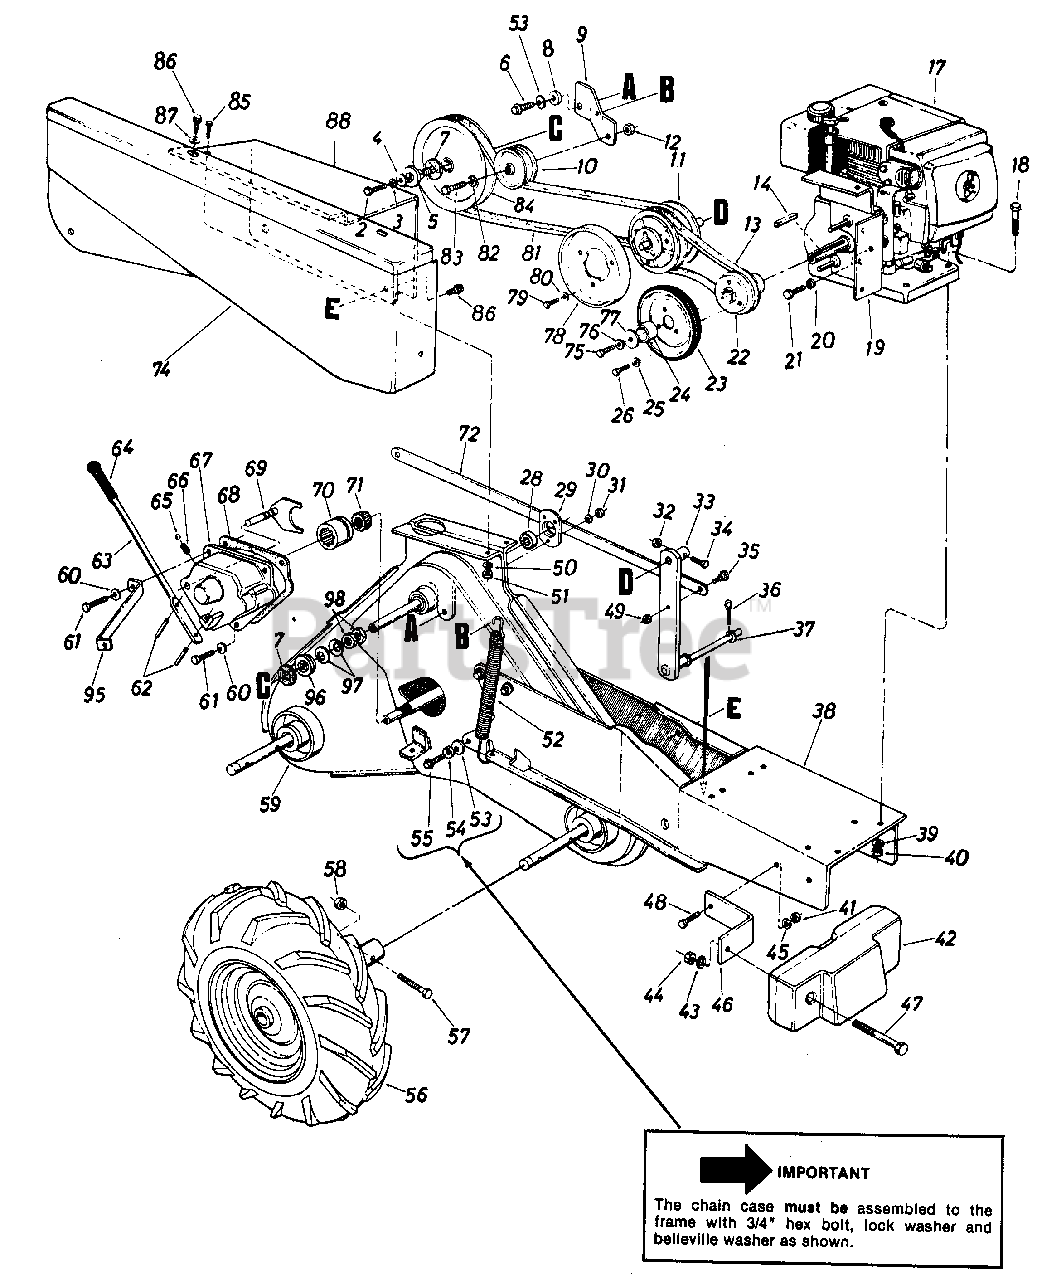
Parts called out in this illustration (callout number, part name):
2	Hex L-Bolt 5/16-24 x 1.5" Lg.*
3	L-Wash. 5/16" I.D.
4	Fl-Wash. 5/16" I.D. x 1.125" O.D.
5	Friction Disc Ass'y.
6	Hex Bolt 3/8-24 x 1.25" Lg.
7	Friction Pad
8	Shoulder Spacer
9	Idler Bracket
10	Fl-ldler 2.75" Dia.
11	Variable Speed Ass'y.
12	Hex Ins. L-Nut 3/8-16 Thd.
13	V-Belt 5/8" x 27.0" Lg.
14	Sq. Key 1/4" x 2.00" Lg.*
17	Engine
18	Hex Bolt 5/16-18 x 1.75" Lg.*
19	Belt Cover Support Ass'y.
20	Internal L-Wash. 1/2" I.D.
21	Hex Bolt 1/2-20 x .75" Lg.
22	Engine Pulley Ass'y.
23	Friction Wheel Ass'y.
24	Spacer
25	L-Wash. 5/16" I.D.*
26	Hex Bolt 5/16-18 x .50" Lg.*
28	Ball Bearing
29	Bearing Housing 1-3/8" O.D.
30	L-Wash. 1/4" I.D.*
31	Hex Nut 1/4-28 Thd.*
32	Hex Ins. L-Nut 1/4-20 Thd.
33	Variable Speed Brkt. Ass'y.
34	Hex Bolt 1/4-20 x 1.25" Lg.*
35	Shld. Bolt 1/2" Dia. x .25" Lg.
36	Cotter Pin 1/8" Dia. x 1.0" Lg.*
37	Fl-Wash. .686" I.D. x 1.25" O.D.
38	Frame Ass'y.
39	L-Wash. 5/16" I.D.*
40	Hex Nut 5/16-18 Thd.*
41	Hex Cent. L-Nut 3/8-24 Thd.
42	Weight
43	Fl-Wash. .50" I.D. x 1.0" O.D.
44	Hex Nut 1/2-13 Thd.*
45	L-Wash. 3/8" I.D.'
46	Weight Mtg. Brkt.
47	Hex Bolt 1/2-13 x 4.50" Lg.*
48	Hex Bolt 3/8-24 x 1.00" Lg.*
49	Hex Ins. L-Nut 3/8-16 Thd.
50	L-Wash. 1/4" I.D.*
51	Hex Cent. L-Nut 1/4-28 Thd.
52	Spring Idler Bracket
53	Belleville Wash. 3/8" I.D.
54	L-Wash. 3/8" I.D.*
55	Hex Self-Tap Scr. 3/8-16 x .75" Lg.
56	Wheel Ass'y. Comp. R.H.
56	Wheel Ass'y. Comp. L.H.
57	Hex Bolt 3/8-24 x 1.25" Lg.*
58	Hex Ins. L-Nut 3/8-24 Thd.
59	Chain Case Ass'y. Comp.
60	L-Wash. 5/16" I.D.*
61	Hex Tap Tite Scr. 5/16-18 x .75" Lg.
62	Headed Spiral Pin 3/16 x 13/16" Lg.
63	Engagement Lever
64	Grip
65	Ball Detent.250" Dia.
66	Compression Spring
67	Shift Housing R.H.
67	Shift Housing L.H.
68	Gasket Shift Housing
69	Shift Yoke Ass'y. R.H.
69	Shift Yoke Ass'y. L.H.
70	Clutch Dog
71	Clutch Dog Driver
72	Control Brkt.
74	Shroud Belt Cover
75	Hex Bolt 7/16-20 x 2.25" Lg.
76	L-Wash. 7/16" I.D.
77	Fl-Wash. .44 I.D. x 1.38" O.D.
78	Friction Disc
79	Hex Bolt 1/4-28 x .50" Lg.
80	L-Wash. 1/4" I.D.*
81	V-Belt 5/8" x 51" Lg.
82	L-Wash. 3/8" I.D.*
83	Hex Bolt 3/8" x 1.50" Lg.*
84	Input Pulley Chain Case
85	Hex Bolt 1/4-28 x .62" Lg.
86	Hex Wash. Hd. Self-Tap Scr.
87	Fl-Wash. 1/4" I.D.
88	Belt Cover Shroud
95	Brace
96	Floating Disc
97	Spring Bell-Wash.
98	Hex Jam Nut 1.0-14
